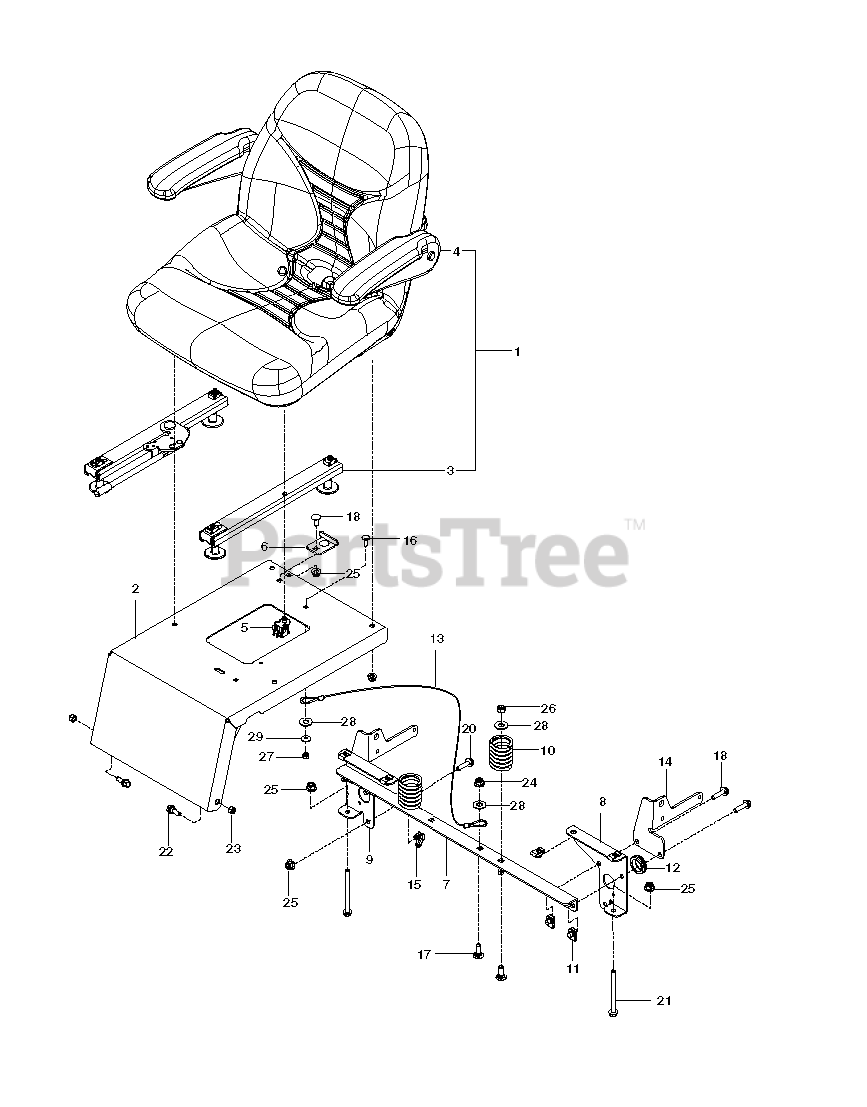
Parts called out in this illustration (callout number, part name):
1	SEAT
2	KIT.SEAT.MOUNT.W/DECAL
3	TRACK ADJUSTMENT KIT
4	ARMREST KIT, LT SQUARE END
5	SWITCH.SNAPMOUNT.NC
6	STOP, SEAT - BLACK
7	SUPPORT, SEAT
8	SUPPORT, LT, BLK
9	SUPPORT, RT, BLK
10	SPRING, SEAT
11	U-CLIP 5/16-18 NUT RETAINER
12	RUBBER GROMMET
13	SEAT LANYARD
14	MOUNT, SEAT BELT, BLACK
15	TIE WRAP, 8-3/8", W/CLIP
16	RHSNB 1/4C X 3/4
17	RHSNB 3/8C X 1
18	RHSNB 5/16-18 X 3/4
20	HHFS 5/16-18 X 3/4
21	HHFS 5/16-18 X 3 3/4
22	SB 5/16-18 HEX HD GD5, BLK ZN
23	NUT 5/16 NYLOC
24	NUT 3/8-16 HEX FLG NYLOC ZD
25	5/16-18 NYLOC FLANGE NUT
26	NUT 3/8-16 NYLOC
27	NUT.1/4-20.HEX.NYLOC.ZD
28	WASHER 3/8 FLAT
29	WASHER 1/4 FLAT
